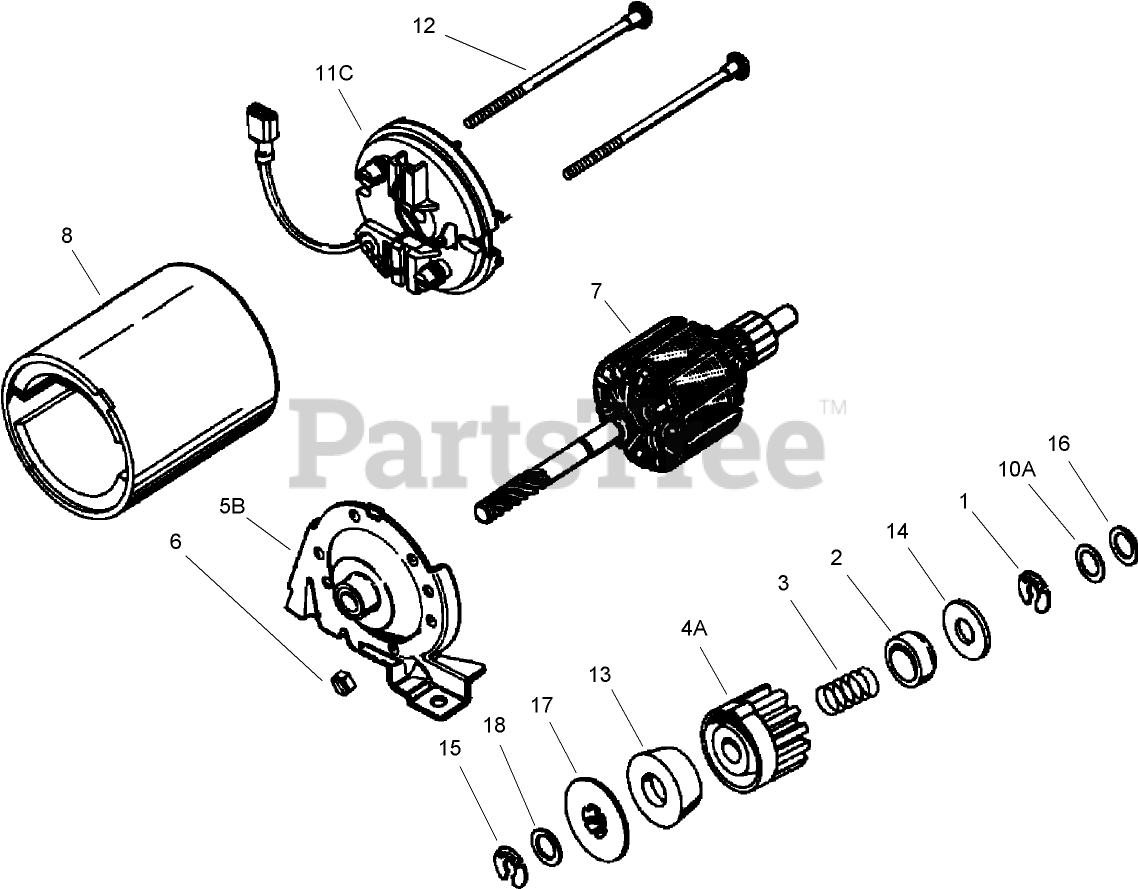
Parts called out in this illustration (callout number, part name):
1	Ring-Retaining
2	Retainer-Spring
3	Spring
4A	Gear
5B	Drive End Cap ASM
6	Nut-Lock
7	Armature
8	Housing ASM
10A	Washer-Thrust
11C	Commutator End Cap Ass-y. (Incl. brushes)
12	Bolt (10-32 x 3-3/16)
13	Driver-Pinion
14	Washer-Cup
15	Ring-Retaining
16	Washer
17	Nut-Drive
18	Washer
